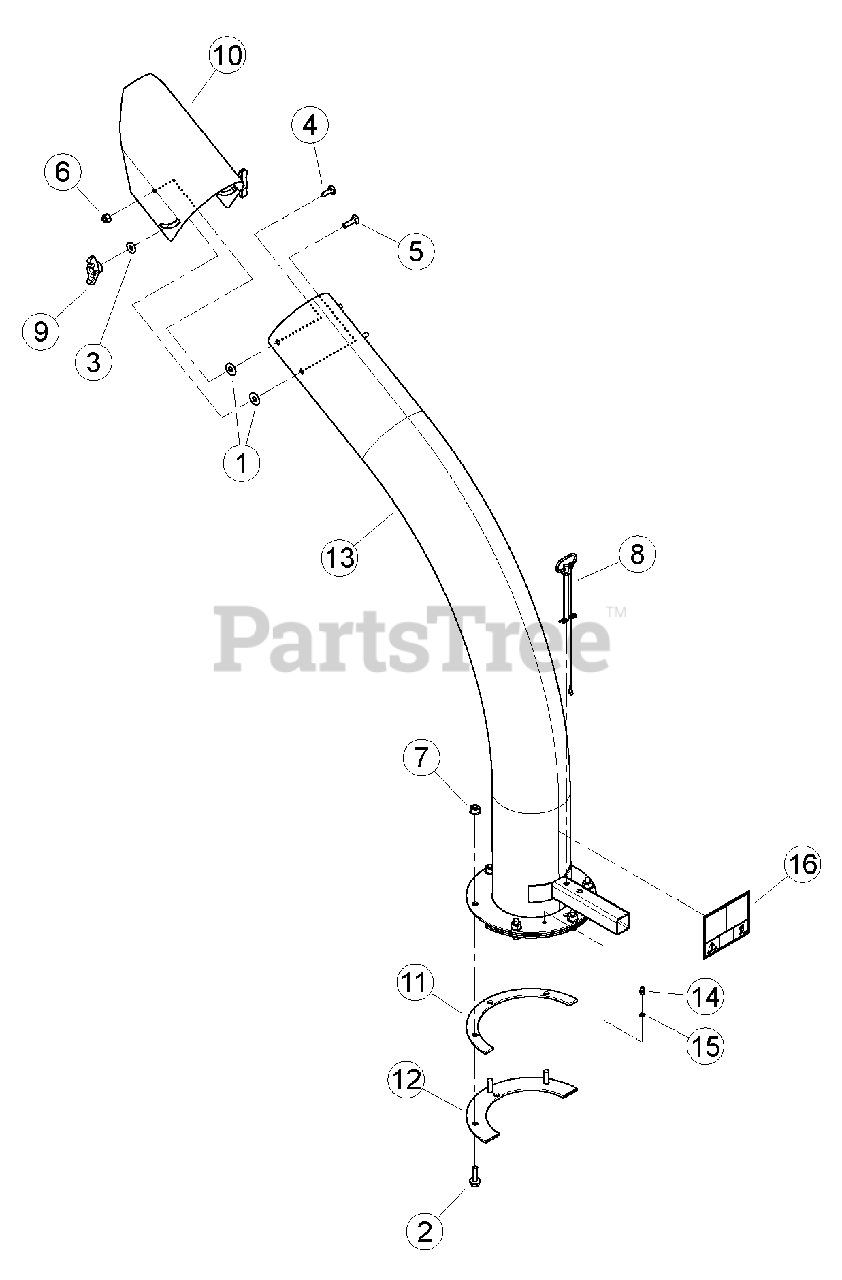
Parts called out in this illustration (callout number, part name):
1	WASHER, 3/8 FLAT
2	BOLT, 3/8 X 1-1/4 FLANGE NC
3	WASHER, 5/16 FLAT
4	BOLT, 5/16-18 X 1 GR5 CRG
5	BOLT, 5/16 X 1-1/4 GR5 CRG
6	NUT, 5/16-18 NYLOCK FLANGE
7	NUT, 3/8-16 NYLOCK FLANGE
8	PIN, 3/8 X 4.25" DISCHARGE
9	KNOB, 5/16-18 UNC TEE W/ LOCKING INSERT
10	DEFLECTOR, BLOWER VAC DISCHARGE
11	SPACER, DISCHARGE PIVOT
12	RING, DISCHARGE CLAMP
13	ASSEMBLY, 6 INCH DISCHARGE CHUTE
14	FITTING, 1/4 SELF-TAP GREASE
15	WASHER, FLAT .254 X .400 X .048
16	DECAL, DISCHARGE DEBRIS & LOCK
